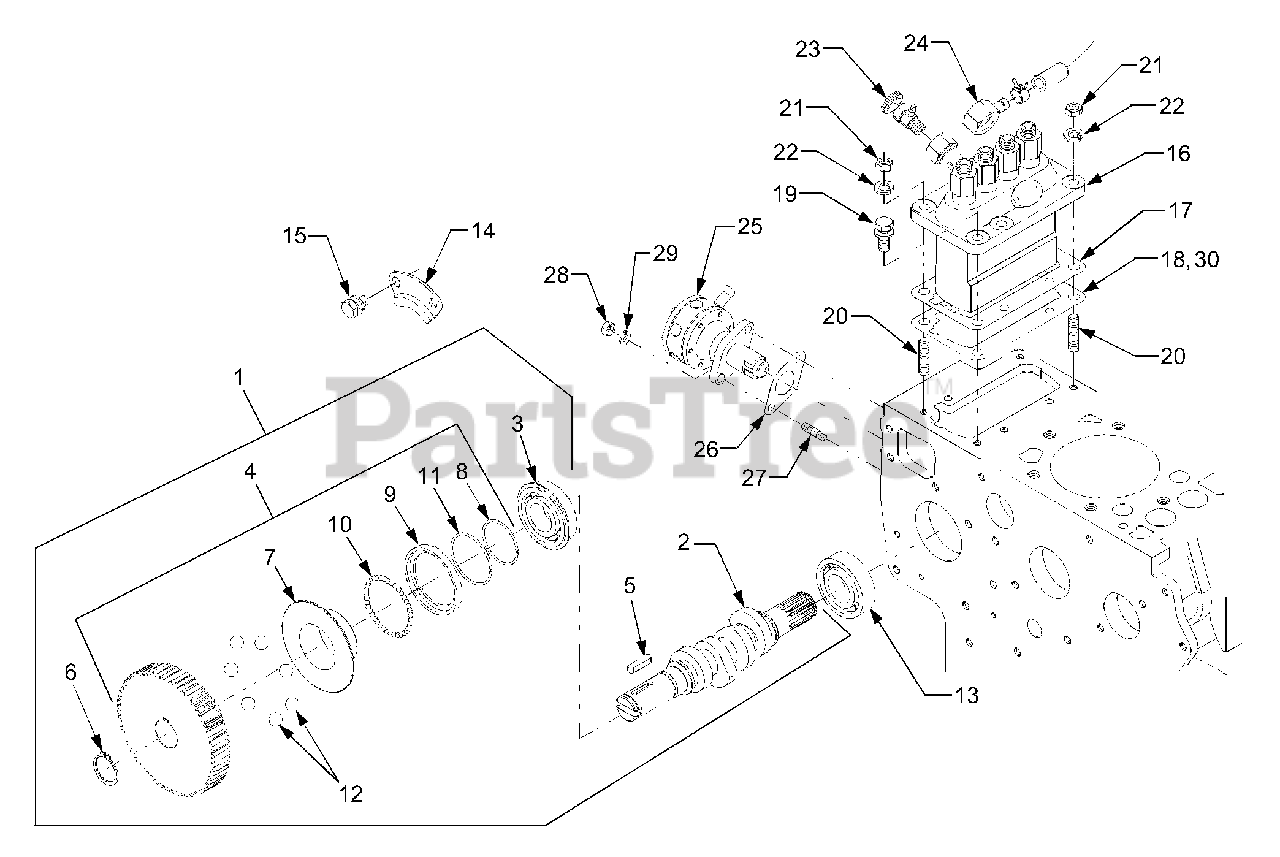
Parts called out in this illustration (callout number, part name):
1	Fuel Camshaft Ass'y
2	Camshaft, Fuel
3	Bearing, Ball
4	Governor Sleeve Ass'y
7	Sleeve, Governor
8	Cir-clip, Sleeve
9	Case, Governor Ball
11	Cir-clip, Ball Case
13	Bearing, Ball
14	Stopper, Fuel Camshaft
16	Injection Pump Ass'y
17	Shim, Injection Pump
18	Shim, Injection Pump
22	Washer, Spring
23	Jet Start Cock Ass'y
24	Joint, Fuel Pipe
25	Fuel Pump Ass'y
26	Gasket, Fuel Pump
29	Washer, Spring
30	Shim, Injection Pump
